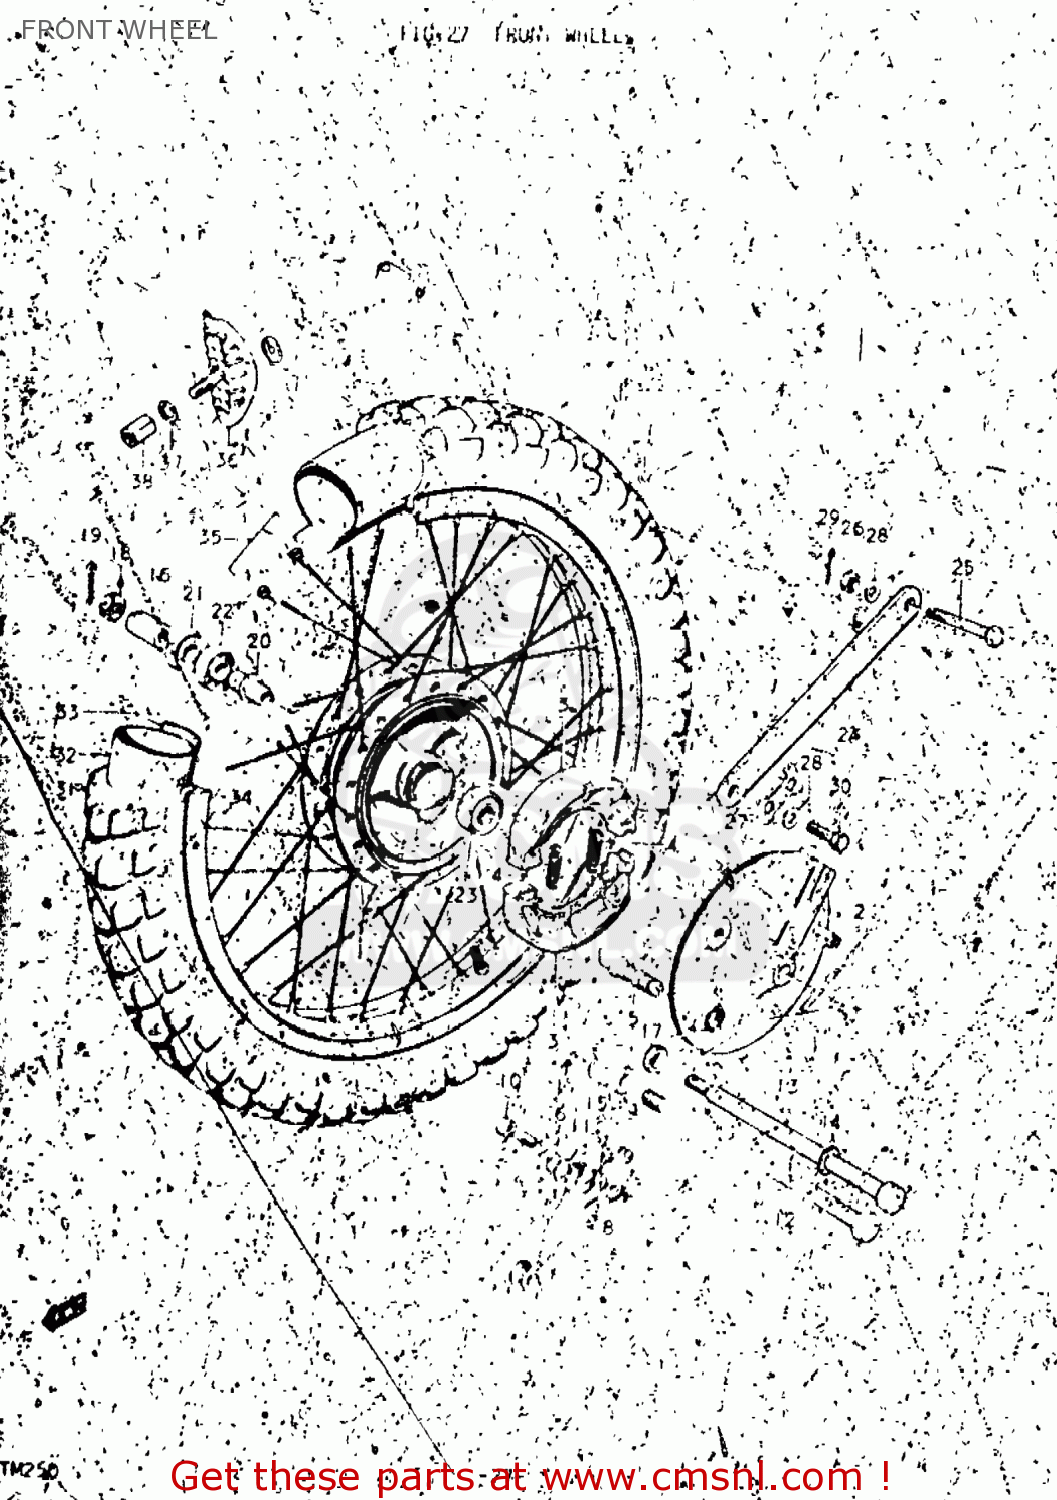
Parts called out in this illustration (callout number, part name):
0	HUB,FRONT
1	HUB,FRONT
2	PANEL,FRONT HUB
3	SHOE,BRAKE
4	SPRING(L:34)
5	CAM,FRONT BRAKE
6	O RING(D:2.5,ID:11.4)
7	LEVER,FRONT BRAKE CAM
8	WASHER
9	NUT
10	BOLT
11	WASHER(12.5X20X1)
12	AXLE,FRONT
13	AXLE,FRONT
14	WASHER
15	NUT,FRONT AXLE
16	SPACER,FRONT AXLE,RIGHT
17	SPACER
18	NUT M
19	COTTER PIN
20	SPACER,FRONT HUB BEARING
21	OIL SEAL(17X38X5)
22	BEARING
23	BEARING, RH
24	LINK, FRONT TORQUE
25	BOLT
26	NUT 8MM
27	MUD FLAP,FRONT FENDER,LEFT
28	WASHER
29	COTTER PIN J,K
30	BOLT
31	TIRE,FRONT
32	TUBE,INNER
33	PROTECTOR,WHEEL,INNER
34	RIM,FRONT WHEEL
35	SPOKE SET
36	STOPPER,BEAD
37	WASHER
38	NUT
